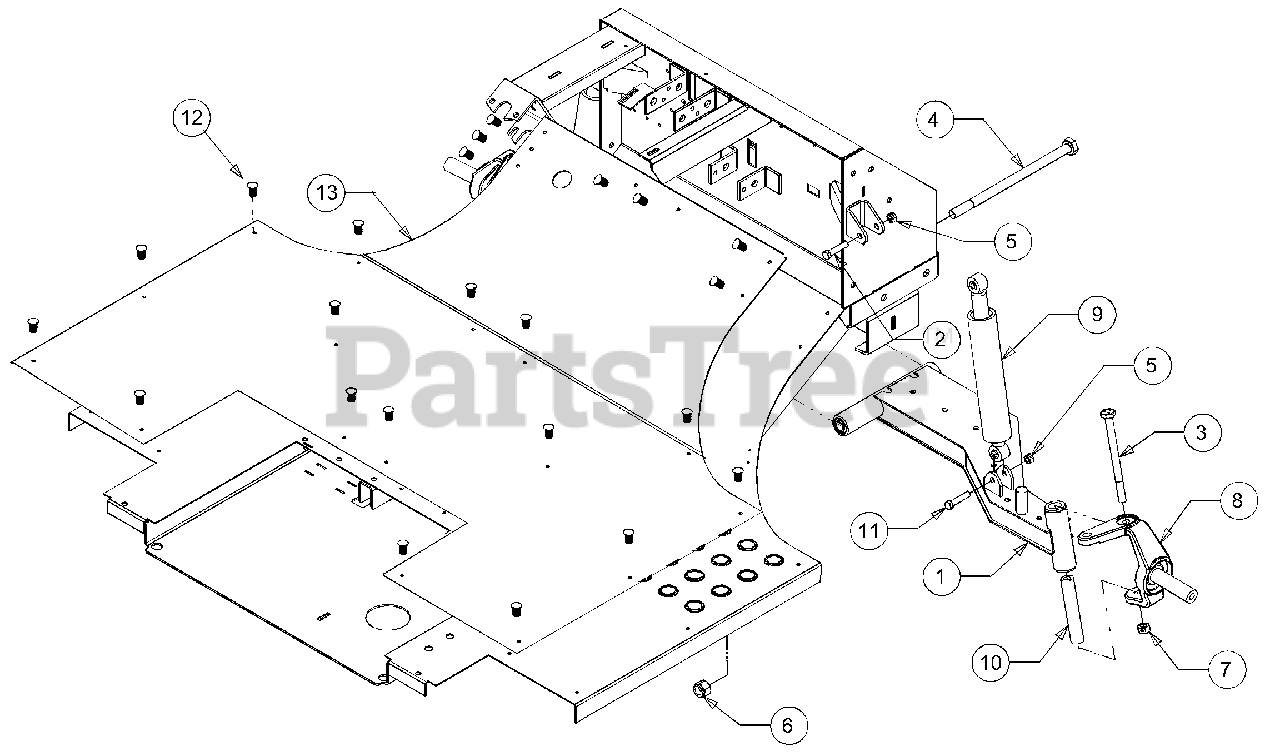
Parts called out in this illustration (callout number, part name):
1	Axle Assembly, Right-front
2	Hex Screw, M10-1.25 x 65mm
3	Hex Screw, 1/2-13 x 6.50, Gr5
4	Hex Screw, 5/8-11 x 11.13, Gr5
5	Nut, Hex Lock, Nylon, M10 -1.25
6	Nut, Hex Lock, Nylon, 5/8-11, Gr5
7	Nut, Hex Lock, 1/2-13
8	Steering Control Knuckle, RH
9	Shock Absorber, 2.9 Stroke
10	Tube, .875 x .50 x 4.75
11	Hex Screw, M10-1.25 x 50mm
12	Clip, Retainer
